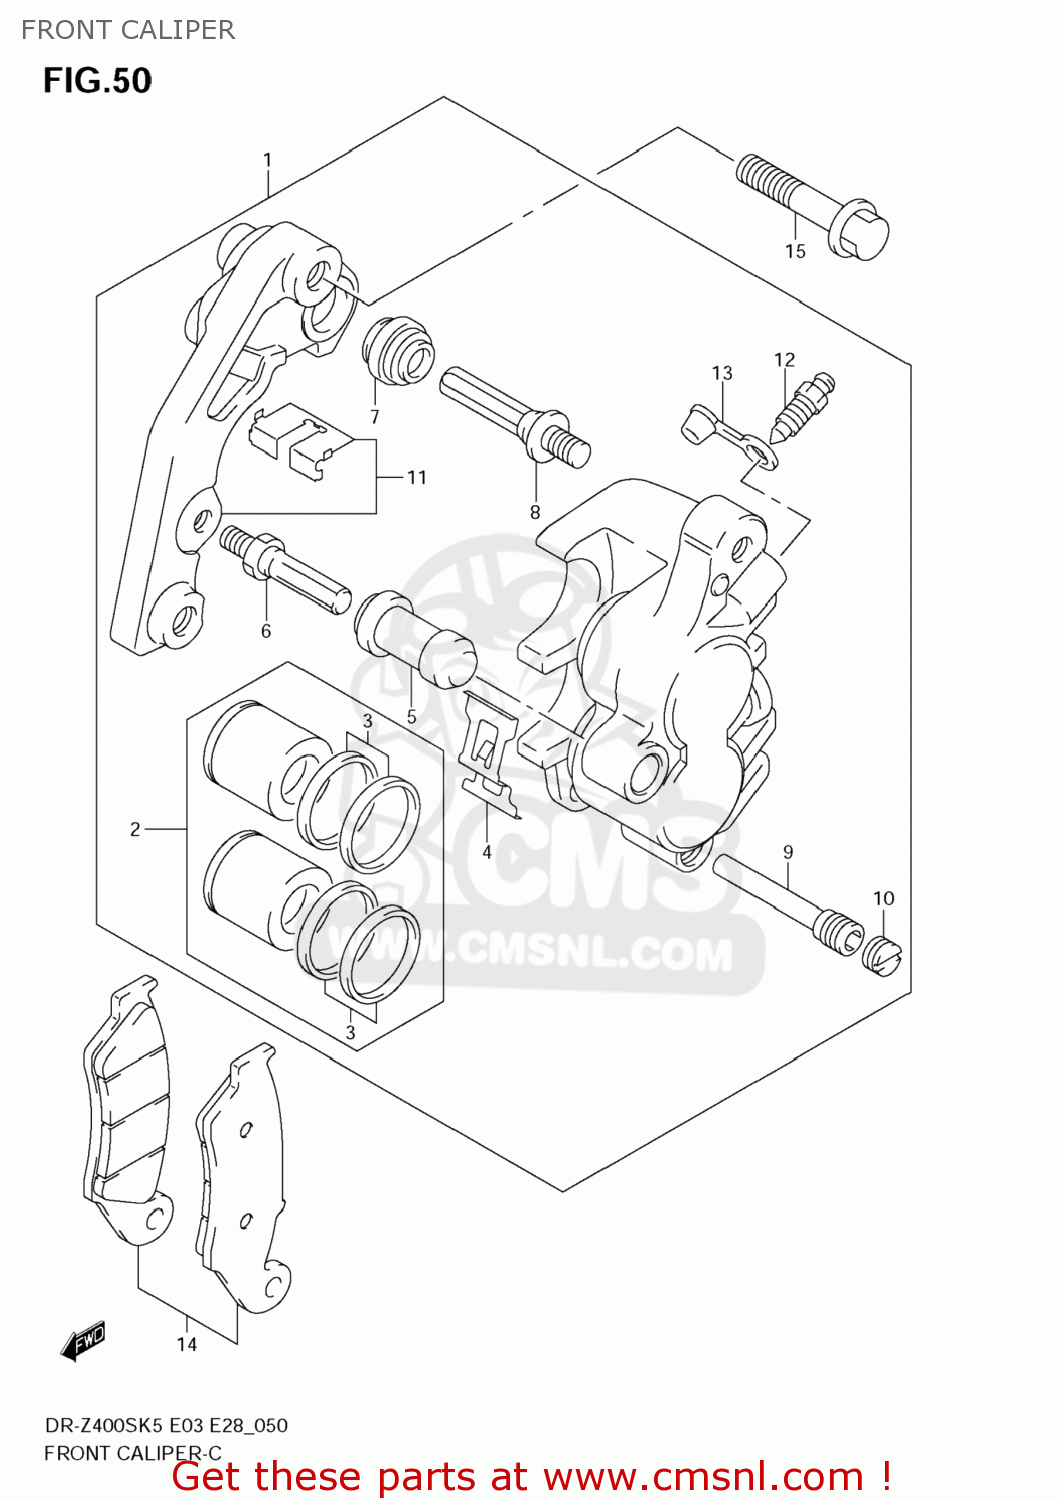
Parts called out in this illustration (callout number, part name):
1	CALIPER ASSY,F
2	PISTON SET
3	SEAL SET,PISTON
4	SPRING,PAD
5	BOOT
6	BOLT
7	BOOT
8	PIN
9	PIN,HANGER
10	PLUG,PIN
11	BRACKET
12	BLEEDER
13	CAP,BLEEDER
14	PAD SET (NAS)
15	BOLT(8X40)
